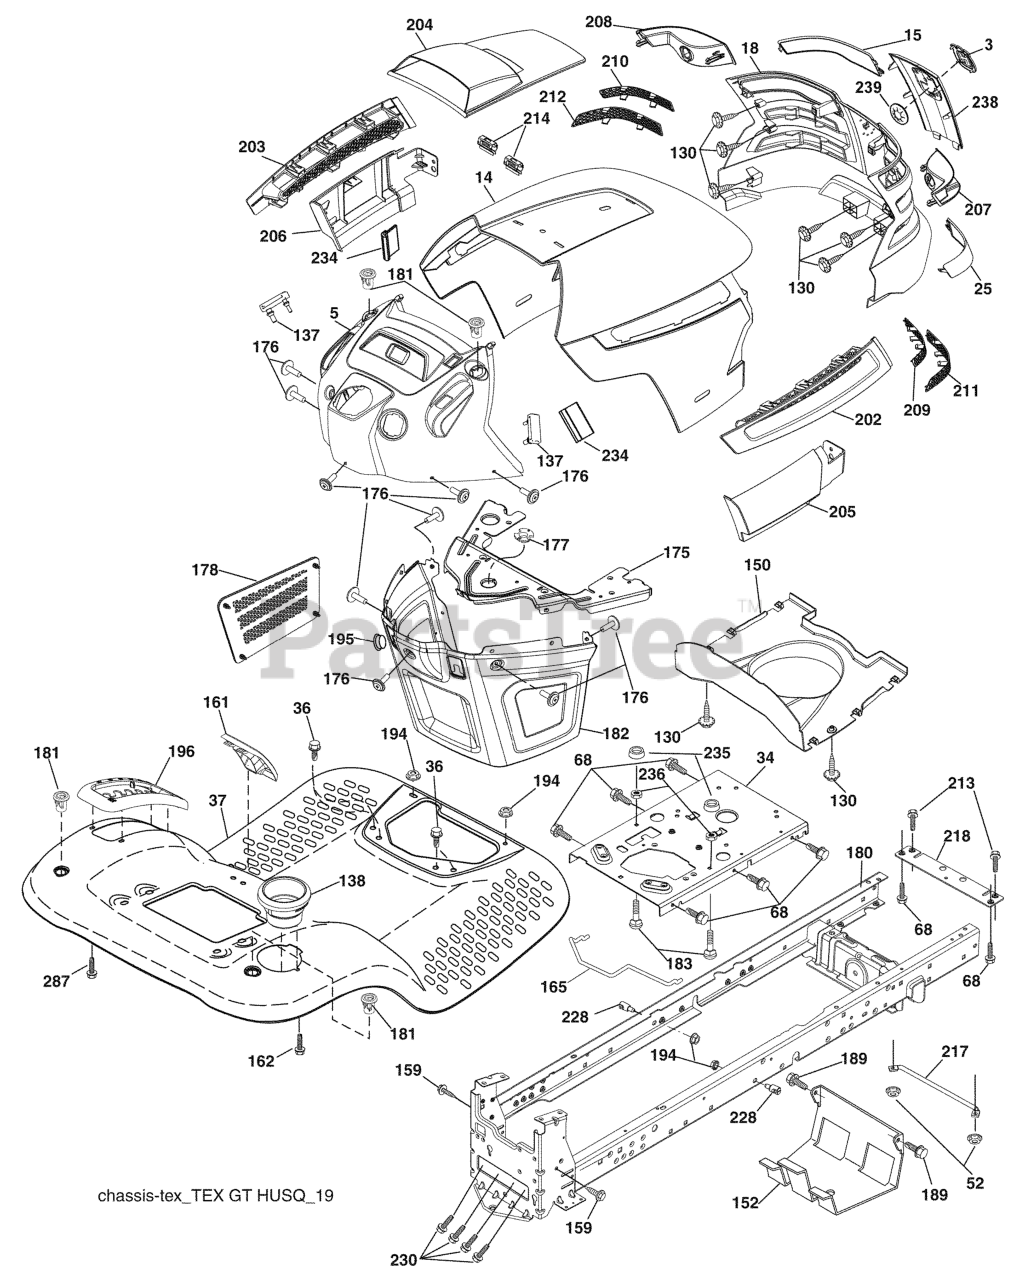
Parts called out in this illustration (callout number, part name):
3	TRIM.HUSQ.TG/CRD.SERVICE
4	RP LOGO
5	DASH.ASM.HUSQ.GT
6	NUT PUSH M
14	HOOD
15	LENS.LH.TEX.GT.HUSQ.CL
18	GRILL.ASM.HUSQ.TG/CRD.W/TRIM
25	LENS.RH.TEX.GT.HUSQ.CL
34	PLATE.ENGINE.WELDED.CHASSIS
36	SCREW 5/16"
37	FENDER.TLT.W/CPH.W/FW.ORANGE
52	LOCKNUT
68	Screw Thdrol 5/16-18 x 1/2
130	SCREW.#10 X 0.750.BOS
137	BUMPER DASH
138	CUPHOLDER.TL.TEX.418
150	AIR.DUCT.TEXGT.HUSQ.SV
152	SHIELD.BROWNING.W/TEX
161	WINDOW FUEL
162	SCREW.HI-LO.CONSOLE
165	SUPPORT.TANK.REAR.W/TEX
175	PLATE.CROSSMEMBER.HUSQ
176	SCREW.#10-24X5/8.RN.QU
177	BUSHING, STEERING
178	CARGO.ASM.NET.TXGT.W/C
180	CHASSIS
181	BUSHING.MNT.FEND.CRGO.
182	DASH.LOWER.COMMON.12V.ADAPTOR
183	BOLT.5/16-18X1-1/4 FULL.THREAD
189	SCREW
194	NUT LOCK HEX FLANGE 5/16-18
195	PLUG.HOLE.DASH.LOWER.12V.BLK
196	RP CONSOLE.ASM.DECKLFT.GR/RBT.
202	VENT.SIDE.HOOD.HUSQ.RH.GREY
203	VENT.SIDE.HOOD.HUSQ.LH.GRAY
204	VENT.ASM.TORPHD.HUSQGT.LOGO.CL
205	SKIRT.HOOD.SIDE.HUSQ.RH.GREY
206	SKIRT.HOOD.SIDE.HUSQ.LH.GREY
207	BEZEL.RH.TEX.GT.HUSQ
208	BEZEL.LH.TEX.GT.HUSQ
209	INSERT.HEX.GRILL.HUSQ.GREY
210	INSERT.HEX.GRILL.HUSQ.
211	INSERT.HEX.GRILL.HUSQ.
212	INSERT.HEX.GRILL.HUSQ.
213	BOLT
214	CLIP.RETAINER.TINNER.
217	ROD.PIVOT.HOOD
218	X-PIECE.HOOD.STOP.NON/
228	STUD.FASTNER.W/ANTI-ROTATE
230	SHOULDER BOLT 5/16-18TT
234	BUMPER.HOOD.TEX.HUSQVARNA
235	SPACER FENDER
236	NUT.CENTERLOCK.5/16-
287	SCREW 1/4X20
